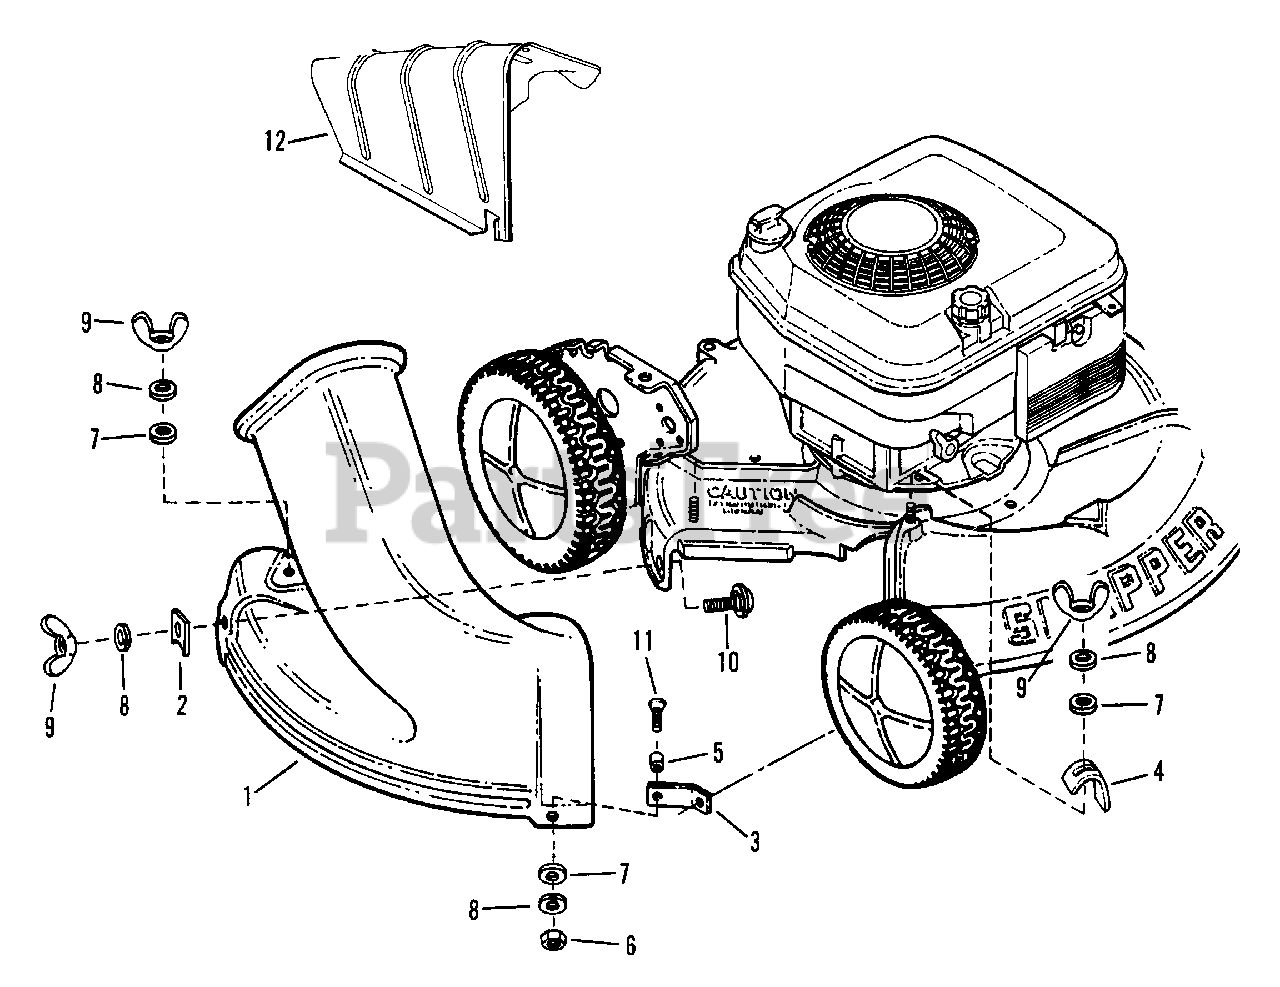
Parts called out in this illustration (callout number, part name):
1	ADAPTER, Grass Bag
2	PLATE, Guide
3	BRACKET, Side
4	CLAMP
6	NUT, 5/16-18 Hex
7	WASHER, 5/16 Flat
8	WASHER, 5/16 Split Lock
9	NUT, 5/16-18 Wing
10	BOLT, 5/16-18 x 1" Carriage
11	SCREW, 5/16-18 x 1-1/8" Flat Head
12	KIT, Side Chute
